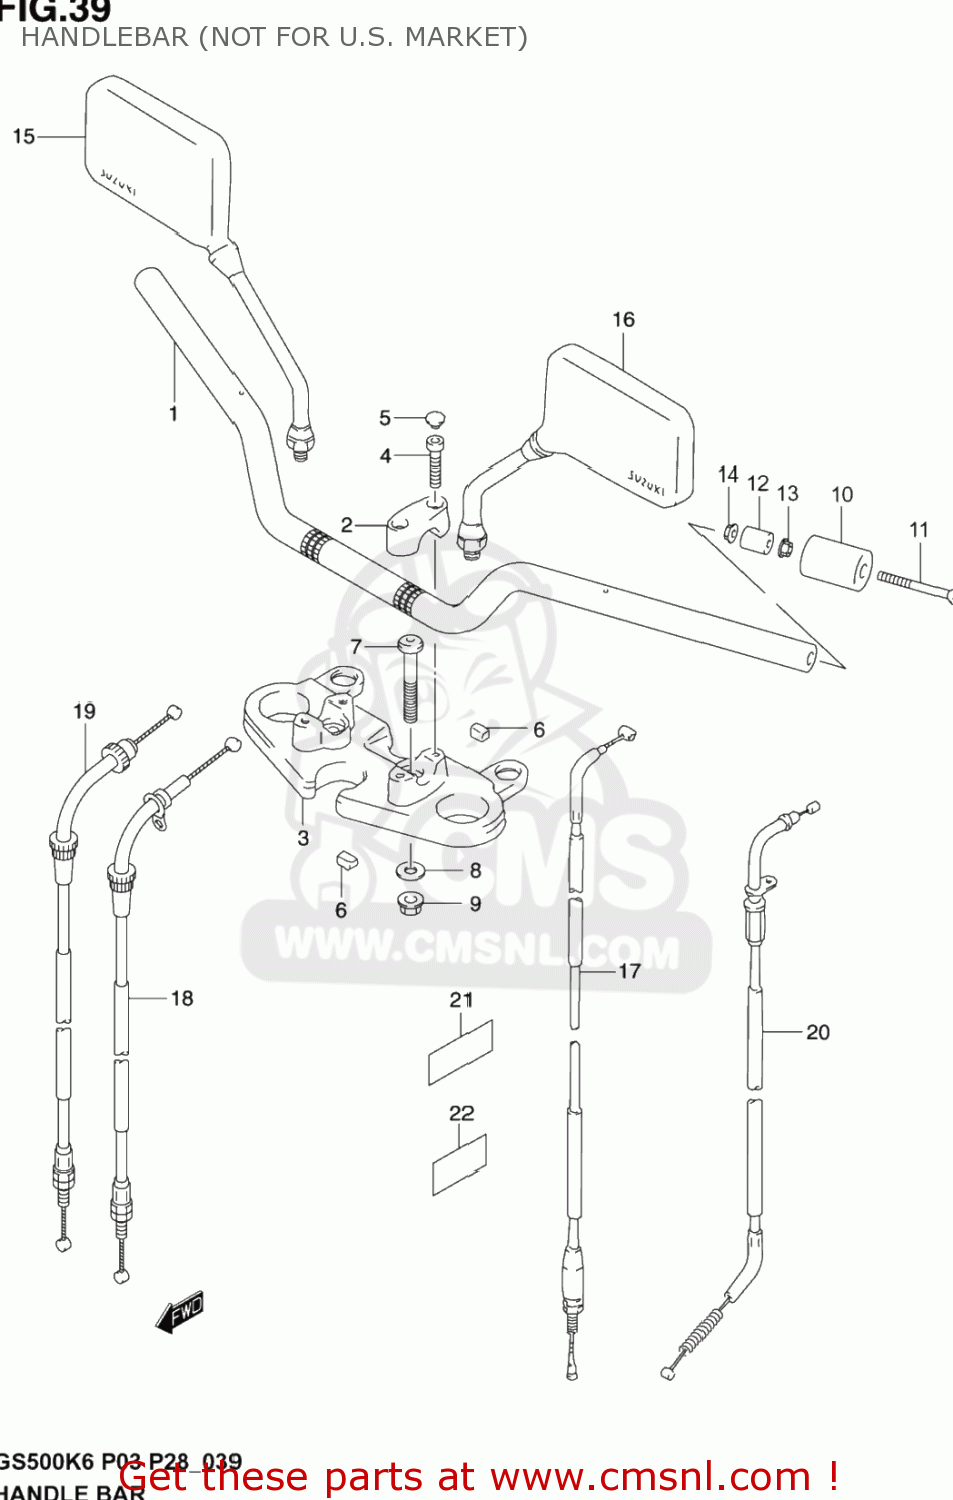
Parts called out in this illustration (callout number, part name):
1	HANDLEBAR
2	CLAMP,HANDLEBAR UPR
3	HOLDER,HANDLEBAR LWR
4	BOLT
5	CAP(OD:11)
6	CUSHION,HANDLE HOLDER
7	BOLT
8	WASHER
9	NUT
10	BALANCER,HANDLEBAR
11	SCREW,HANDLE B
12	EXPANDER,HANDLE BALANCER
13	NUT
14	NUT
15	MIRROR ASSEMBLY,REAR VIEW
16	MIRROR ASSEMBLY,REAR VIEW
17	CABLE ASSY,CLUTCH
18	CABLE ASSY,THROTTLE NO.1
19	CABLE ASSY,THROTTLE NO.2
20	CABLE,STARTER
21	PROTECTOR, CABLE
22	PROTECTOR, CABLE
